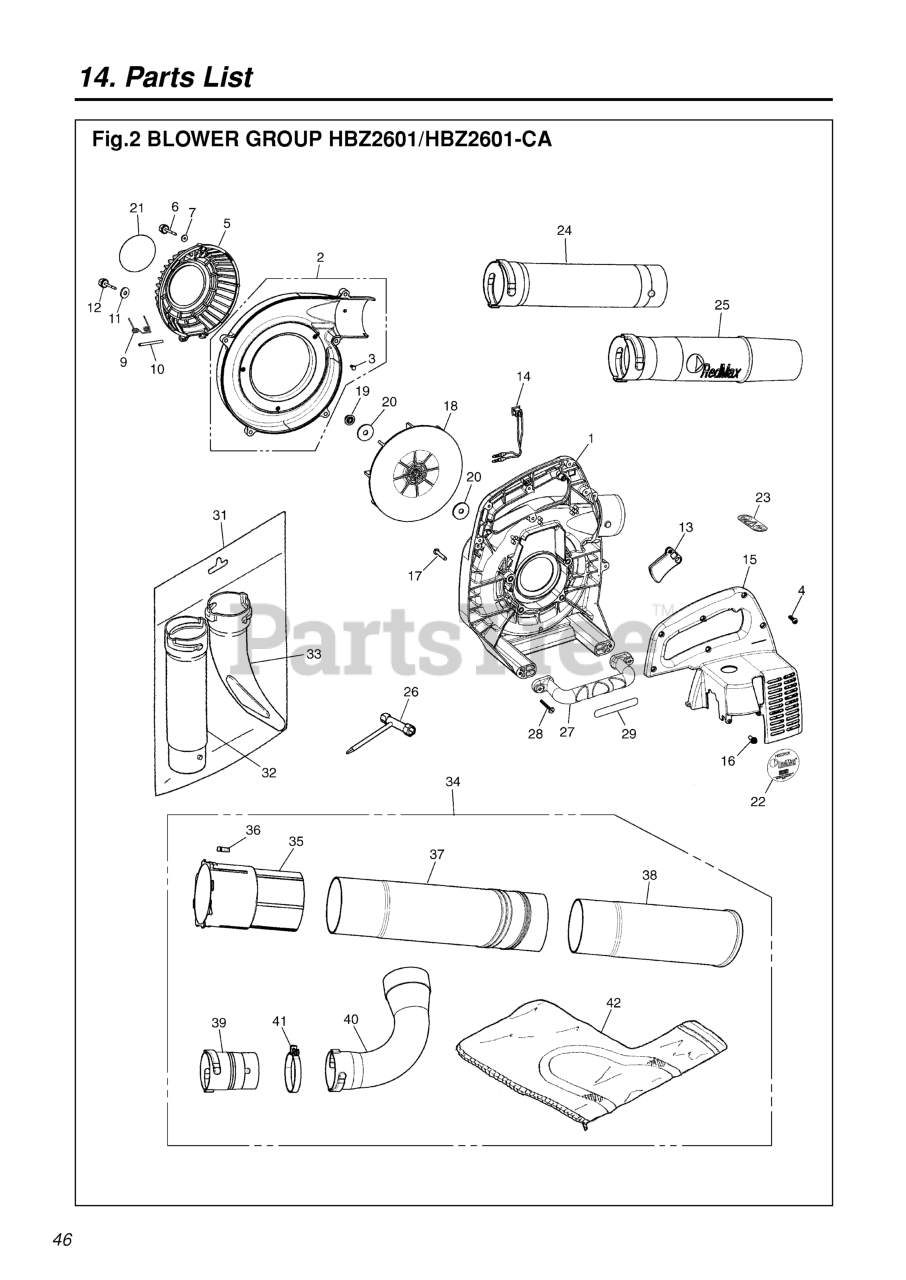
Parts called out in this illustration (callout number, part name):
1	VOLUTE CASE
2	VOLUTE COVER ASSY
3	SCREW
4	SCREW TORX
5	GUARD NET
6	SCREW
7	WASHER
9	SPRING
10	SHAFT
13	LEVER
14	SWITCH
15	ENGINE COVER
16	BOLT TORX
17	SCREW TORX
18	FAN
19	NUT
20	WASHER
21	LABEL, CAUTION
22	LABEL, RECOIL
23	LABEL, CE CAUTION
24	PIPE, STRAIGHT
25	PIPE, END
27	HANDLE
28	SCREW
31	FLAT NOZZLE SET
32	PIPE, STRAIGHT
33	FLAT NOZZLE
34	VACUUM KIT
35	PIPE, A
37	PIPE, B
38	PIPE, C
39	EXTENSION
40	ELBOW
41	CLAMP
42	BAG, DUST
